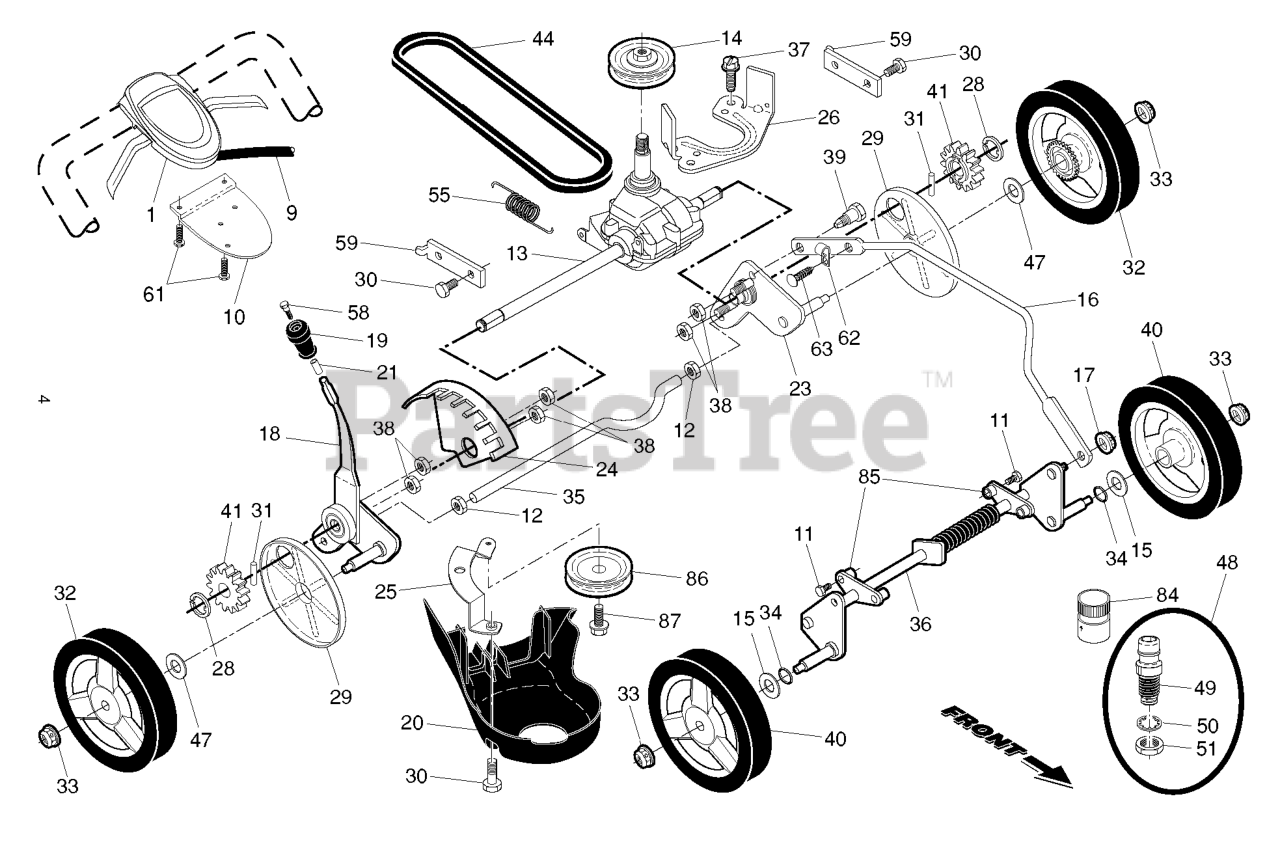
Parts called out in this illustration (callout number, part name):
1	CONTROL.AW2.22+RG.BS.GEN.BK/BK
9	CABLE.DRIVE.RWD.WALK.
10	BRACKET.DRIVE.CONTR.GEN2.BLACK
11	SCREW.HX.13X.750
12	NUT.HEX.1/2-20
13	TRANSMISSION.22+AWD.WALK.MOWER
15	WASHER.FLAT.1/2
16	ROD.CONNECTING.RGD.22+.HW.BLAC
17	NUT.LOCK.5/16-18
18	KIT.SELECTOR.ASM.437869
19	KNOB.SEL.SPRING.22+.SP.RIB.BLK
20	COVER.REAR.DRIVE.22+2013
21	SCREW.PLASTIC.ANCHOR.5/16
23	ADJUSTER.ARM.ASM.AX.RT.SP.ZC
24	BRACKET.WHL.ADJ.9.POS.W/PAD
25	BRACKET.DRIVE.COVER.RGD.
26	BRACKET.TRANS.BELT.KEEPER.BZP
28	E-RING 7/16 RE
29	COVER.DUST.WHEEL.INNER.WALK
30	BOLT.5/16HEX.WHS.HD
31	PAWL, DRIVE
32	WHEEL.8X1.75.3SPK.RAD3.GREY
33	NUT.HEX.FLANGE.3/8-16.LO(3 2)
34	O-RING..070X.487.NEOPRENE
35	AXLE.REAR.RGD
36	AXLE.ASM.FRONT.RGD.CLEAR.ZINC
38	NUT.HEX.FLANGE.1/4
39	SHOULDER BOLT SEMI GIMLET PT.
40	WHEEL & TIRES ASSY, FRONT
41	PINIION.14.TOOTH.RGD
44	RP.BELT.DRIVE.RGD.SS.WALK
47	WASHER FLUT
48	KIT.WASH-OUT.PORT.ZINC.WALK
49	WASHOUT.PORT.ZINC.RGD.22+
50	WASHER.LOCK.INTERNAL.TOOTH
51	LOCKNUT.HEX.WITH.O-RING
55	SPRING.RETURN.AUTO.
58	SCREW.12-14X1.500
59	BRACKET.SUPPORT.22+RWGD.BZP
61	SCREW, PHILLIPS HEAD 10 X 5/8
62	CLIP.CABLE.BLK
63	FASTENER.PUSH.O.250X0.783
84	COUPLING.QUICK CONNECT
85	BRACKET.FRT.AXLE.SUPPORT
86	RP PULLEY.AWD.IDLER
